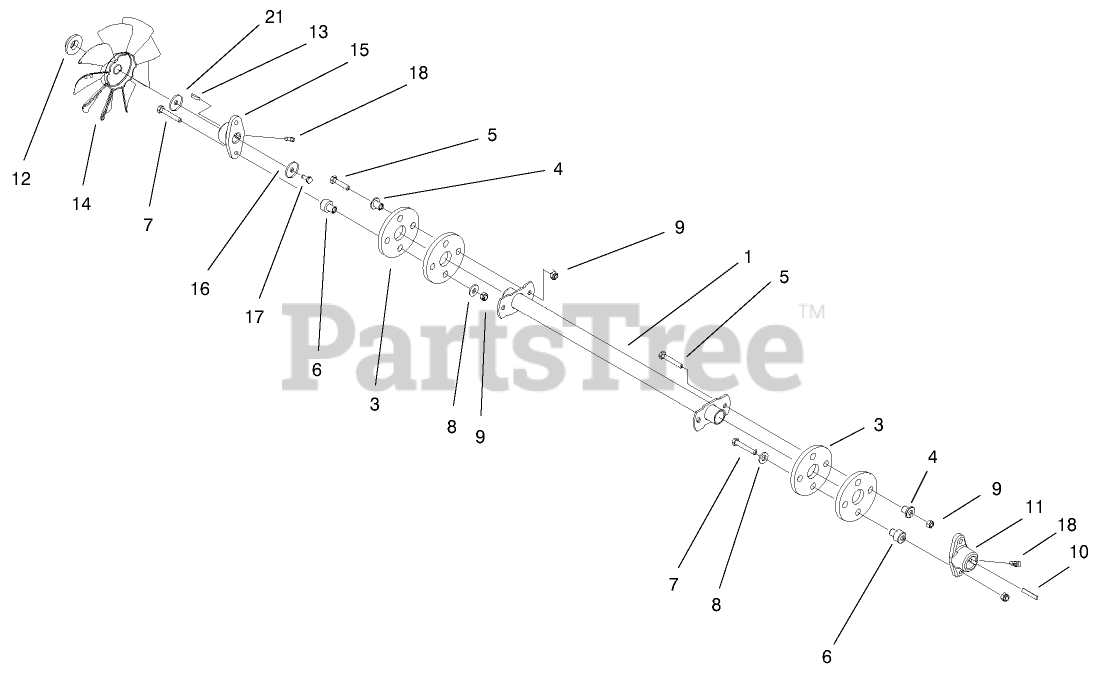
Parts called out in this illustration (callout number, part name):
1	SHAFT-DRIVE
3	COUPLING-RUBBER
4	SPACER
5	SCREW-HH
6	SPACER
7	SCREW-HH
8	WASHER-FLAT
9	NUT-LOCK, NI
10	KEY-SQUARE
12	SPACER-FAN
13	KEY-WOODRUFF
14	FAN-HYDRO
16	WASHER
17	SCREW-HH
18	SCREW-SET
21	WASHER - FAN
